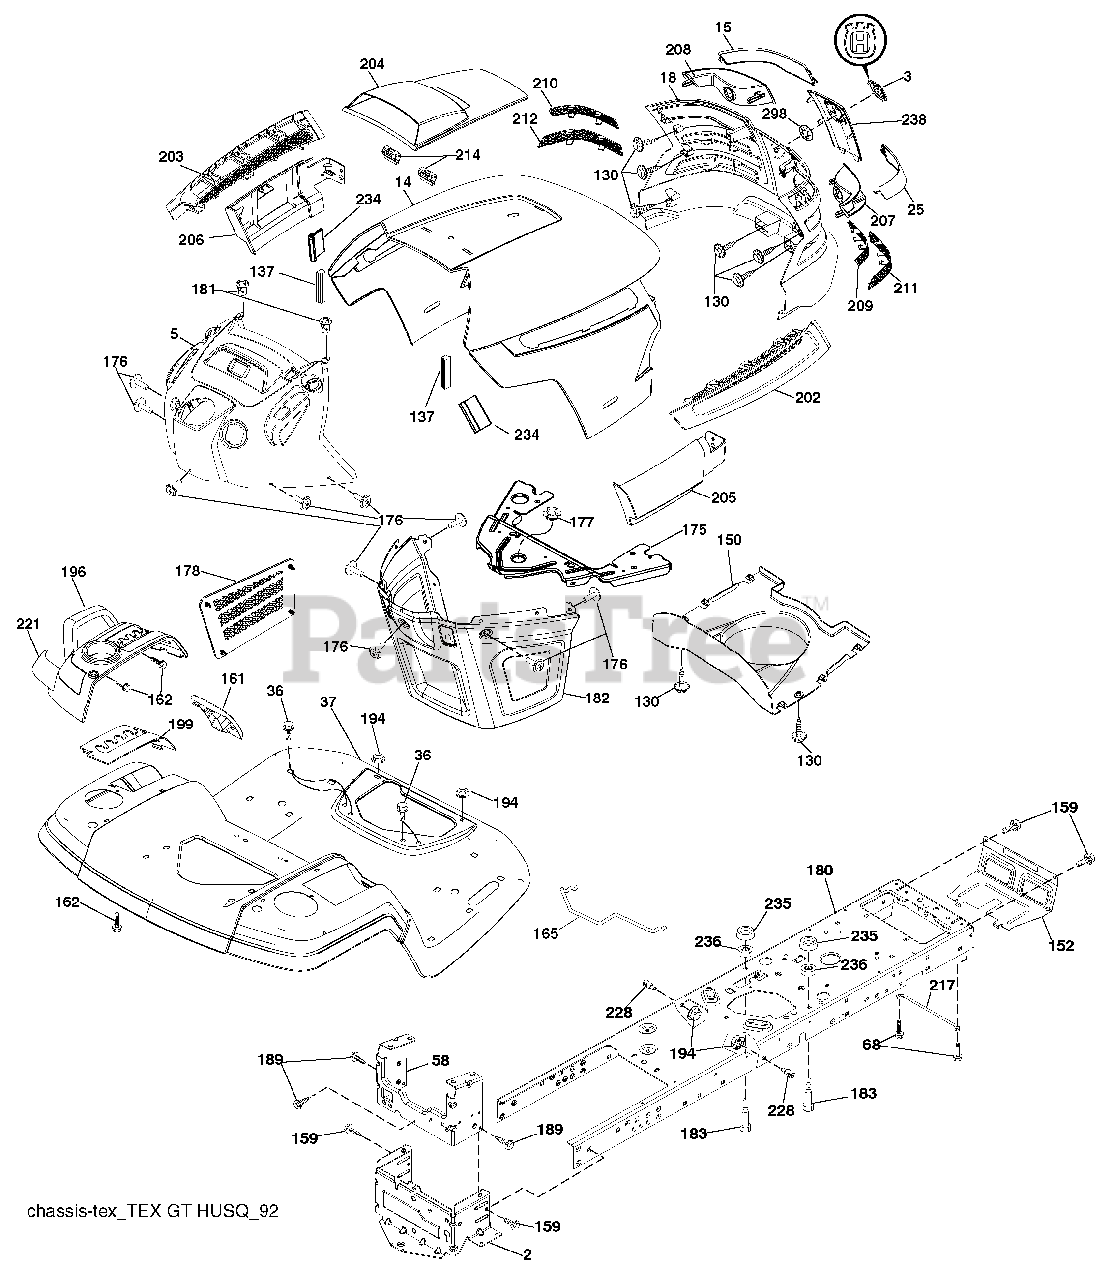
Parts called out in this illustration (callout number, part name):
2	Drawbar Lower
3	Logo
14	Hood
18	Grille/Lens Asm.
36	Screw 5/16-18 x 3/4
37	Fender
58	Drawbar Upper 2pc Lrg Fender
68	Screw Thdrol 5/16-18 x 1/2
130	Screw 10 x 0.750 BOS Thread
137	Bumper Dash
152	Shield Browning
159	Screw 3/8-16 x 3/4
161	Window Fuel
162	Screw Hex Wsh Hi-Lo 1/4 x 1/2 unc
165	Support Tank Rear
175	Crossmember
176	Screw 10-24 x 5/8
177	Bushing Steering
178	Cargo Net Asm.
180	Chassis
181	Bushing Mtg. Fender Crgo
182	Dash Lower
183	Bolt 5/16-18 x 1-1/4
189	Screw 5/16-18 x 3/4
194	Nut Lock Hex Flange 5/16-18
196	Console Asm Dck Lft
199	Plate Deck Lift
202	Vent Side Hood RH
203	Vent Side Hood LH
204	Vent Top Hood
205	Skirt Hood Side RH
206	Skirt Hood Side LH
209	Insert Hex Top RH
210	Insert Hex Top LH
211	Insert Hex Bottom RH
212	Insert Hex Bottom LH
214	Clip Retainer Tinner
221	Reflector LH
228	Stud Fastener
234	Bumper Hood
235	Spacer Fender
236	Nut Lock 5/16-18 unc
238	Trim, Husq.
